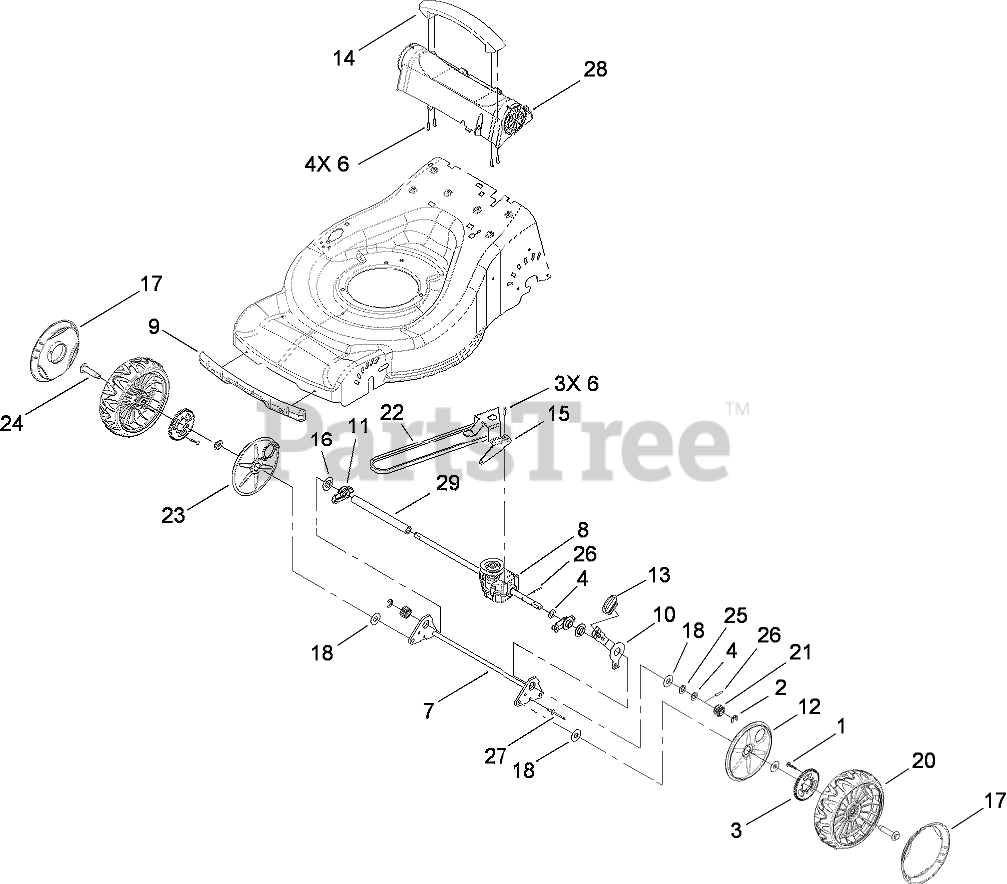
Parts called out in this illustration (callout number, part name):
1	SCREW-DRIVE
2	RING-CLIP, LOCKING
3	GEAR-WHEEL, 52T
4	WASHER-THRUST, KEYED
6	SCREW-TORX, PAN HEAD
7	PIVOT BAR ASM
8	GEARBOX ASM
9	BUMPER-FRONT
10	LEVER-HOC, REAR
11	BUSHING-CAMLOCK
12	COVER-WHEEL
13	KNOB-HOC
14	HANDLE-REAR
15	BRACKET-GEAR CASE
16	SPACER-FLANGE
17	COVER-WHEEL, REAR
18	WASHER-PLAIN
20	REAR WHEEL ASM
21	GEAR-PINION, 15T
22	V-BELT
23	WASHER-STEPPED
24	BOLT-SHOULDER
25	WASHER-THRUST
26	PIN-ROLL
27	RIVET-POP
28	MOUNT-HANDLE
29	SPACER
